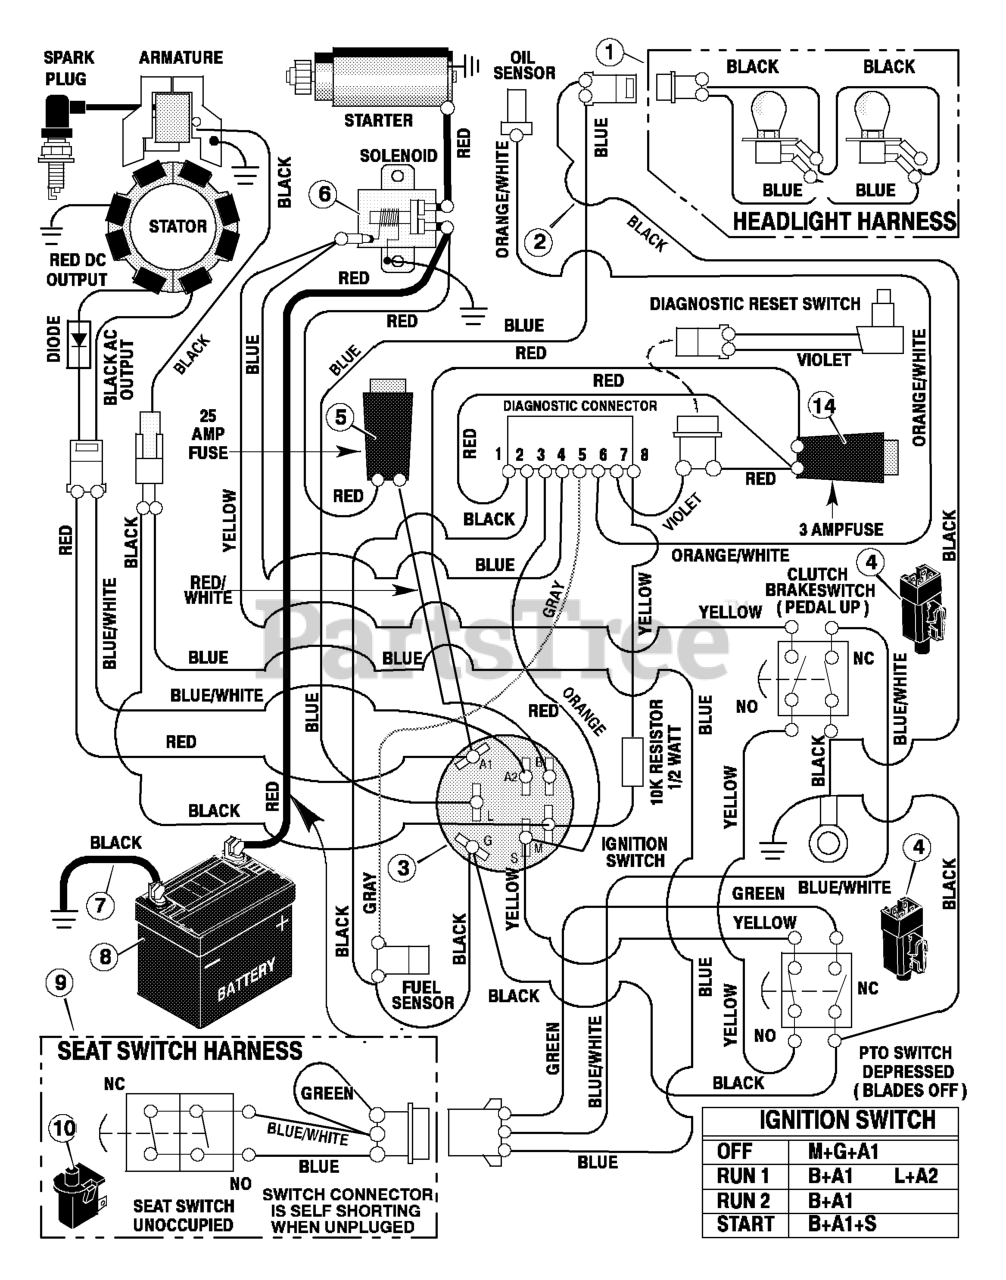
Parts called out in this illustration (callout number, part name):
1	Harness, Light Wire
2	Harness, Chassis Wire
3	Switch, Ignition
4	Switch, Limit
5	Fuse, 25 AMP
6	Solenoid
7	Cable, Battery Ground
8	Battery
9	Harness, Seat Switch Wire
10	Switch, Seat Sensor
14	Fuse, 3 AMP
